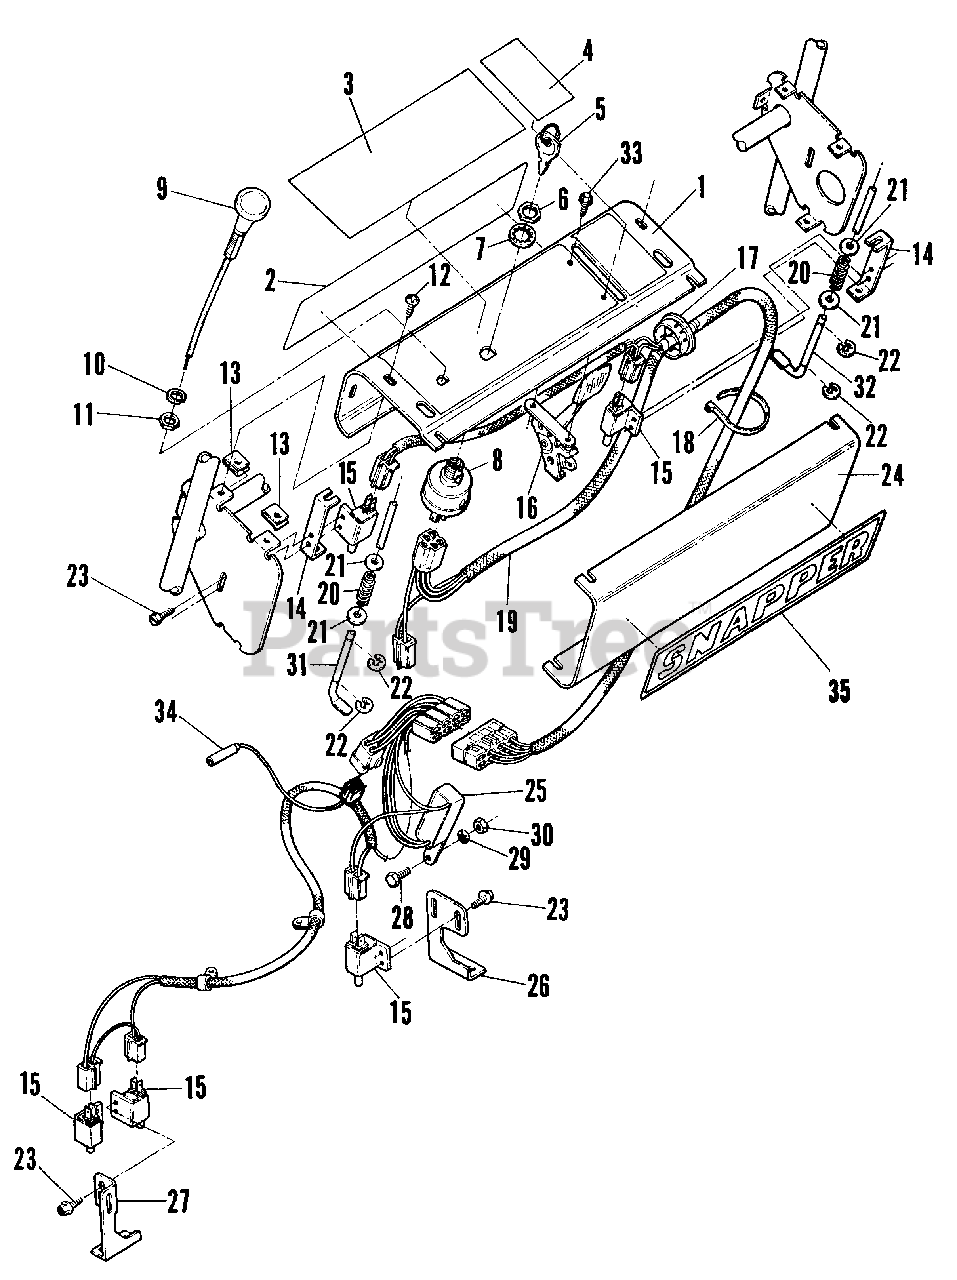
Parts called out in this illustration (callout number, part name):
1	PANEL, Control W/Decals
2	DECAL, "SNAPPER"
3	DECAL, Control Panel
4	DECAL, Caution
5	KEY
6	NUT, Hex 5/8 - 32
7	WASHER, Internal Tooth 5/8
8	SWITCH, Key
9	CABLE, Choke Assembly
10	WASHER, Lock 3/8
11	NUT, Hex Jam 3/8 - 24
12	SCREW, Pan Head 10 - 24 x 5/8
13	NUT, Clip
14	BRACKET, Switch
15	SWITCH, Operator Presence
16	CONTROL, Throttle w/Knob
17	BUSHING, Snap
18	TIE, Plastic Wire
19	HARNESS, Upper Wiring
20	SPRING, Operator Presence
21	WASHER, Flat SAE 1/4
23	SCREW, Thread Forming Hex Head 12-14 x 1/2
24	COVER, Lower W/Decal
25	HARNESS, Module
26	BRACKET, Switch Right
27	BRACKET, Switch Left
28	SCREW, Hex Head Cap 1/4-20 x 3/4
29	WASHER, Internal Tooth Lock 1/4
30	NUT, Nyloc Hex - 1/4 - 20
31	LINKAGE, Operator Presence, Right
32	LINKAGE, Operator Presence, Left
33	SCREW, #10-24 x 1/2" Hex Washer Self-Tap (Torx)
34	HARNESS, Engine Kill
35	LABEL, SNAPPER
